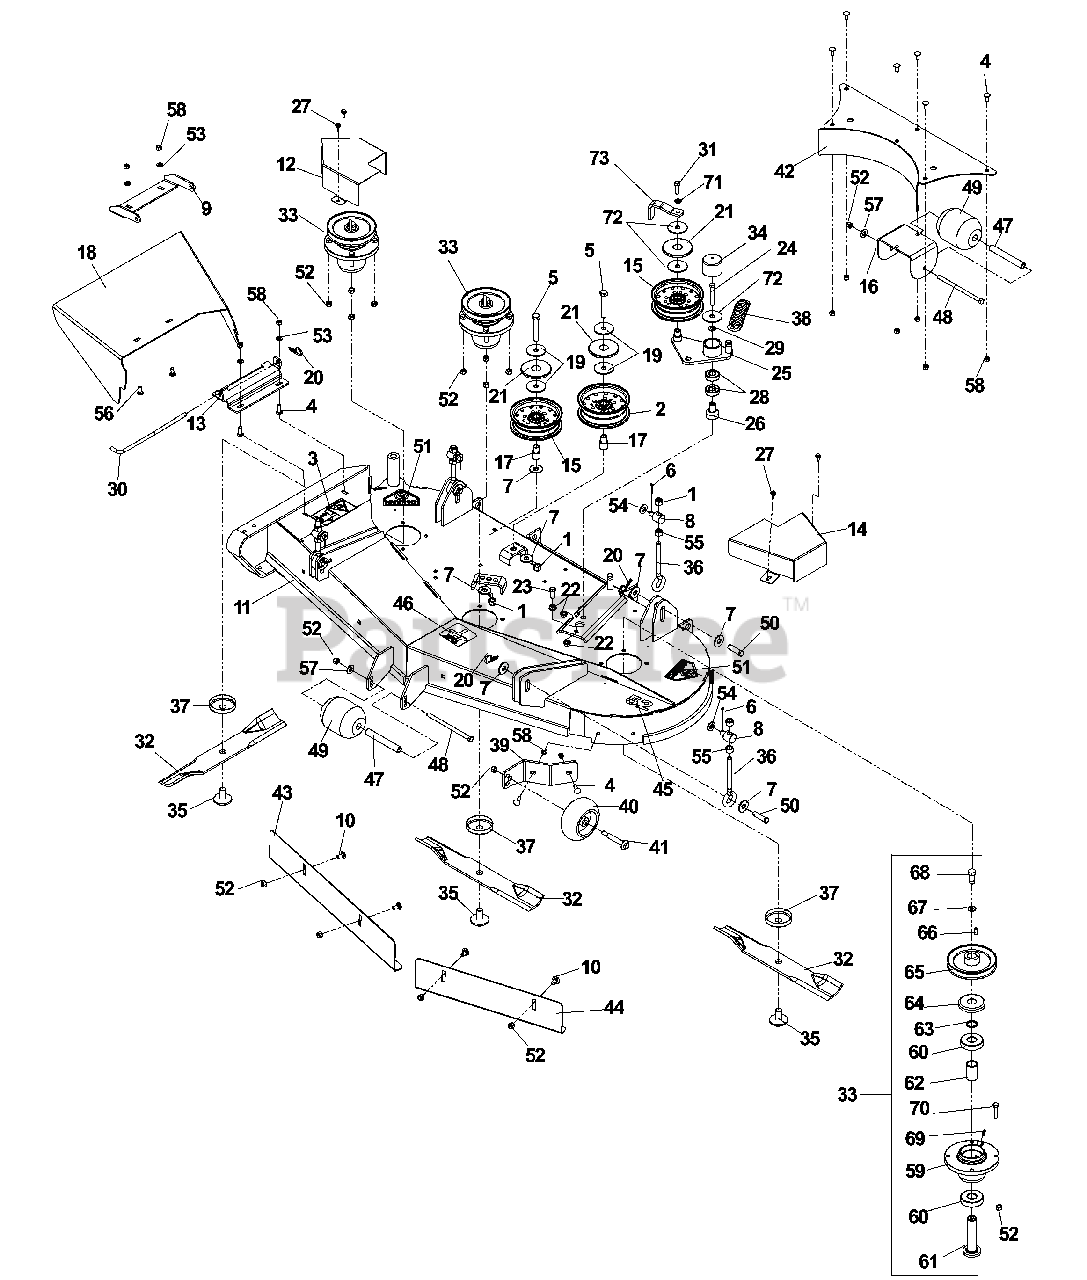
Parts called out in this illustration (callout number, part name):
1	NUT 1/2-13 HEX NYLOC ZD
2	IDLER PULLEY (TALL)
3	DECAL, EURO SEVERING
4	RHSSNB 5/16C X 1.0
5	SCREW, 1/2C X 3 HEX CAP
6	PIN COTTER 1/8 X 1 ZD
7	WASH USS FLAT 1/2
9	HINGE, DISCHARGE CHUTE, BLUE
10	RHSNB 3/8-16 X 3/4 GR5 ZD
11	DECK W/DECAL 52 KODIAK
12	PULLEY GUARD RH BLACK
13	SUPT - CHUTE HINGE PAINTED
14	PULLEY GUARD 52 LH BLACK
15	IDLER PULLEY
16	REAR CENTER ROLLER BKT 52 CLK
17	SPACER - IDLER
18	CHUTE - 52 PAINTED
19	ISOLATOR WASHER
20	PIN, COTTER 1 3/4
21	TOP DUST CAP
22	NUT 3/8C WHIZ
23	HCS 3/8C X 1
24	HCS 3/8C X 2 1/2
25	ARM, IDLER - WELDMENT
26	BEARING PIVOT SPACER
27	SCREW, TAP & DR #12-14 X 3/4
28	BEARING, BALL
29	WASHER 3/8 SAE FLAT
30	DEFLECTOR PIN
31	HCS 3/8C X 1 1/4 GR5
32	BLD 52HFS HI LIFT FUS
33	SPINDLE ASM.
34	CAP, VINYL
35	BLADE BOLT/WASHER
36	BOLT, EYE
37	TRASH GUARD
38	DECK SPRING
39	BRACKET
40	GUAGE WHEEL
41	SHOULDER BOLT
42	W-BAFFLE WLDT.
43	BLOW-BY BAFFLE 52` LH
44	BLOW-BY BAFFLE 52` RH
45	DECAL ORANGE 52`
46	DECAL, BELT ROUTING (18656)
47	BUSHING
48	3/8-16 X 6-1/2 HHB GR8
49	ROLLER 3-3/4 DIA. X 4-1
50	CLEVIS PIN 1/2X1-3/4LG
51	DECAL, CPSC
52	NUT 3/8-16 NYLOC
53	FLAT WASHER 5/16 SAE
54	WASHER 1/2" FLAT
55	NUT HEX 1/2
56	BOLT 5/16C X 3/4" CARRIAGE
57	WASHER 3/8 FLAT
58	NUT 5/16 NYLOC
59	DECK HUB MACHINED
60	BEARING - 6305 - 2RS
61	SHAFT SHORT
63	LIFT TAB
64	TRASH GUARD
65	METRIC PULLEY
66	KEY - 1/4 X .88
67	WASHER .525 X 1.375 X .25
68	1/2-20 UNF X 1 1/4 HHBLT
69	ZERK, 3/16, DRIVE IN
70	HCS 3/8C X 1 1/2
71	SLW 3/8 STD
72	WASHER, 3/8 SPEC
73	GUIDE, BELT
